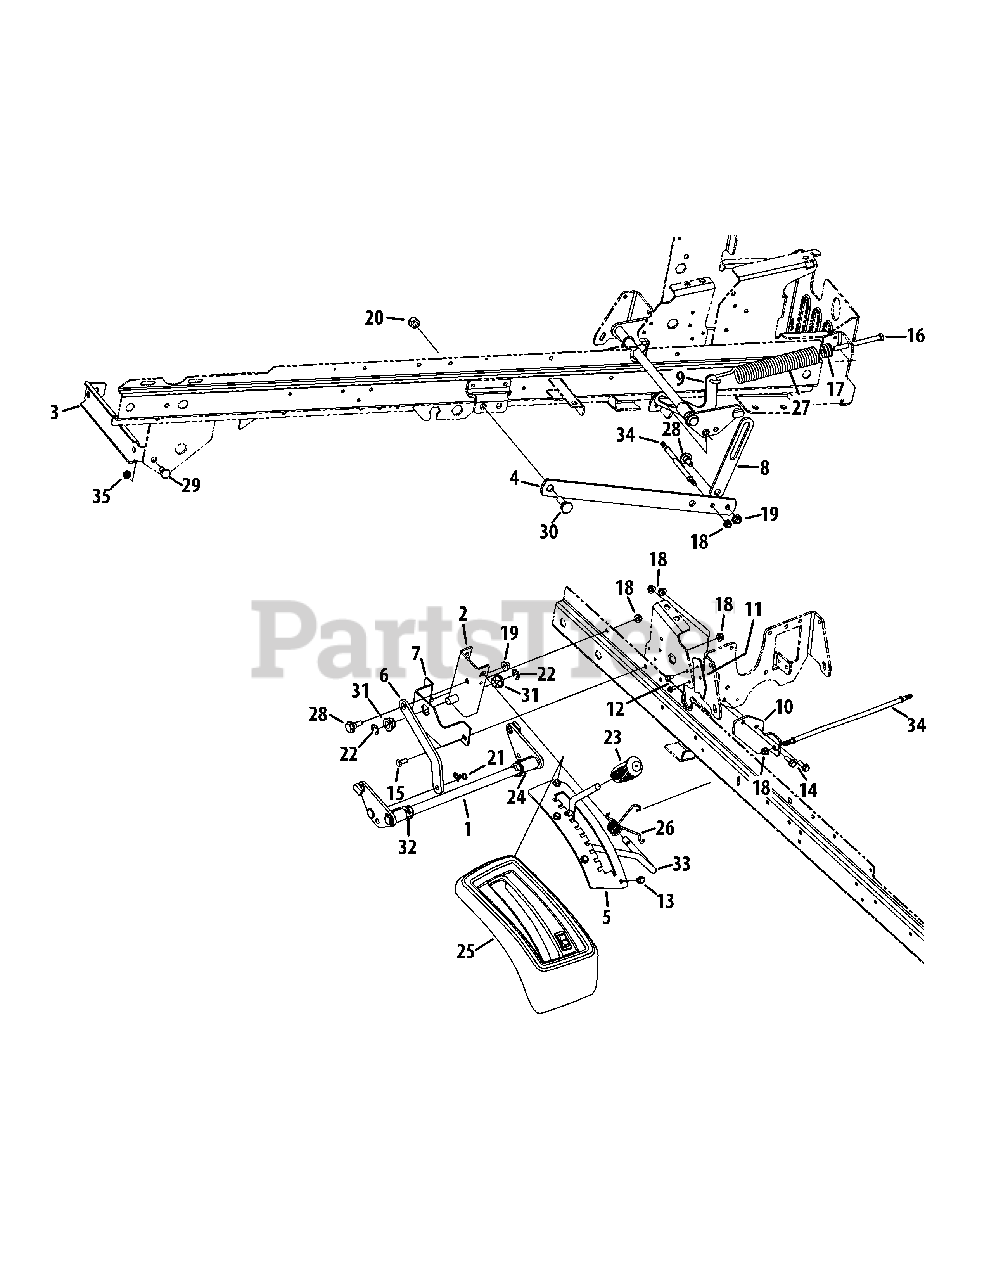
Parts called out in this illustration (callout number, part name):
1	Manual Lift Shaft Assembly
2	Manual Lift Lever Bracket Assembly
3	Front Hanger Bracket
5	Manual Lift Index Bracket
6	Manual Lift Link Plate
7	Manual Lift Lever Mount Bracket
8	Link Lift Plate
9	Extension Spring Plate
10	Sway Bar Mount Bracket
11	Bearing Stop Plate
12	Hex Washer Screw, 1/4-20 x .500
13	Hex Washer Screw, 5/16-18 x .625
14	Hex Washer Screw, 5/16-18 x .875
15	Hex Screw, 5/16-18 x .75
16	Hex Screw, 3/8-16 x 4.25
17	Spring Insert
18	Flange Lock Nut, 5/16-18
19	Flange Lock Nut, 3/8-16
20	Hex Lock Nut, 1/2-13
21	Bow-Tie Cotter Pin
22	E-Ring, .625
25	Lif Manual Cover
26	LH Torsion Spring
27	Extension Spring, 1.485 x 9.68
28	Shoulder Screw, 3/8-16 x .562 x .360
29	Shoulder Screw, 1/2 x .29
30	Shoulder Screw, 1/2-13 x .625 x .36
31	Hex Flange Bearing
32	Hex Flange Bearing
33	Manual Lift Handle Rod
34	Anti-Sway Deck Rod
35	Jam Lock Nut, 3/8-16
